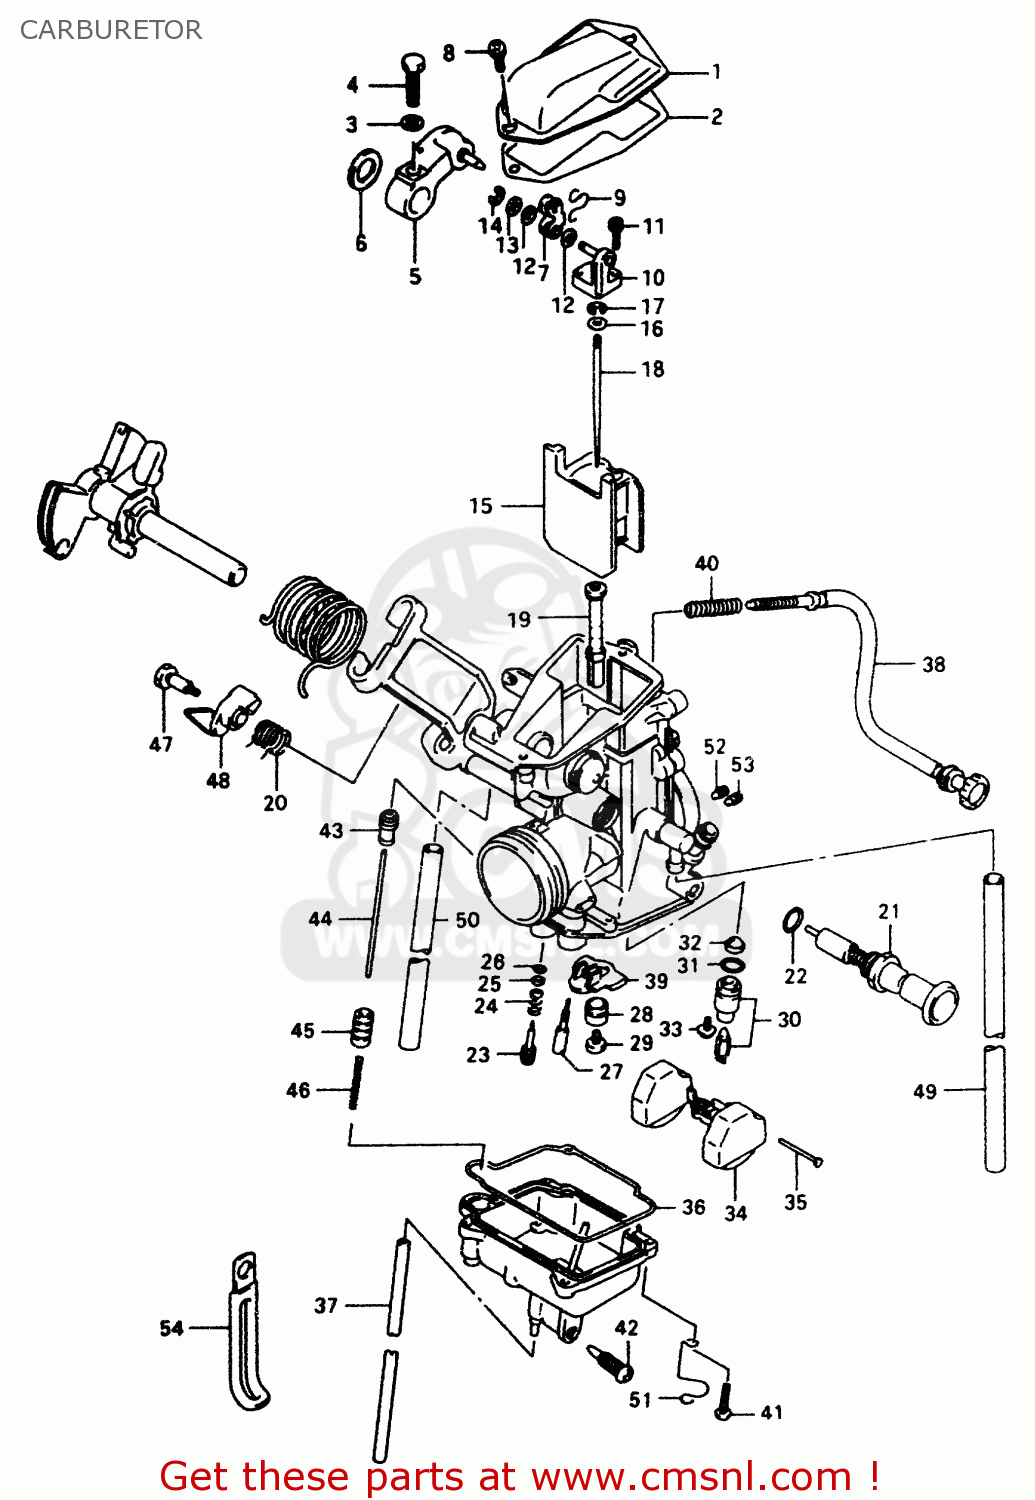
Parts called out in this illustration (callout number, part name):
1	COVER,CARBURETOR,TOP
2	GASKET,CARBURETOR TOP (NAS)
3	LOCK,WASHER
4	BOLT
5	LEVER SET,THROTTLE
6	RING,THROTTLE SHAFT
7	PLATE
8	SCREW
9	SPRING
10	CONNECTOR
11	SCREW
12	GASKET (NAS)
13	WASHER
14	E RING
15	VALVE,PISTON
16	WASHER,JET NEEDLE
17	CLIP
18	NEEDLE,JET
19	JET,NEEDLE(P-8)
20	SPRING
21	PLUNGER ASSY
22	O RING
23	SCREW,PILOT
24	SPRING
25	WASHER
26	O RING,PILOT AIR SCREW
27	JET,PILOT(37.5)
28	RING,MAIN JET FIXING
29	JET,MAIN(127.5)
30	VALVE ASSEMBLY,NEEDLE
31	O-RING,NEEDLE VALVE
32	FILTER
33	SCREW
34	FLOAT
35	PIN,FLOAT
36	O RING,FLOAT CHAMBER
37	HOSE(3X5X600)
38	ADJUSTER ASSY
39	RING
40	SPRING
41	SCREW
42	SCREW,DRAIN
43	BOOT, ACCELE PUMP ROD
44	ROD
45	PLUNGER
46	SPRING
47	BOLT
48	LEVER
49	HOSE(5X9X600)
50	HOSE(5X9X600)
51	CLIP
52	JET,MAIN AIR(0.7)
53	JET,AIR(1.1)
54	CLAMP(L:45)
